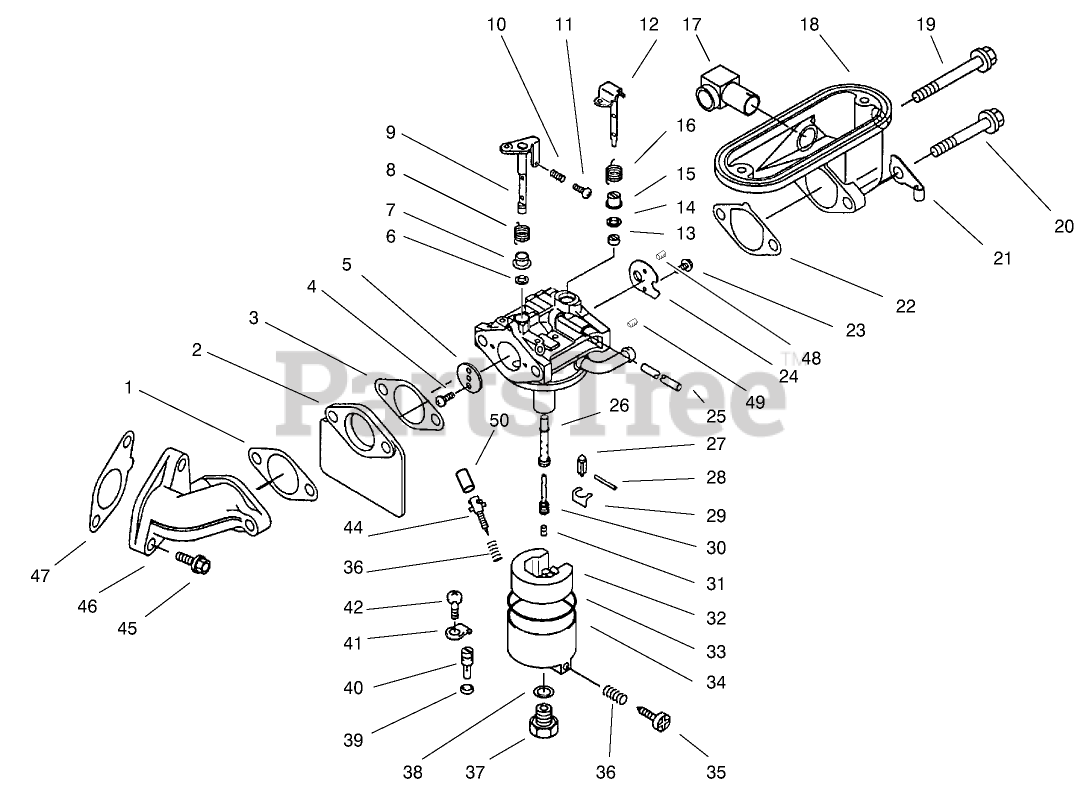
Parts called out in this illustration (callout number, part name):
1	Gasket
3	Gasket-Carburetor
4	Screw
5	Valve-Throttle #110
9	Shaft-Throttle
12	Shaft-Choke
18	Pipe-Intake
22	Gasket
23	Screw
24	Valve-Choke
25	Tube
26	Nozzle-Main
27	Valve-Float
30	Holder-Main Jet
31	Jet-Main
33	Gasket
34	Chamber-Float
35	Screw
38	Gasket
44	Screw-Pilot Air
45	Bolt-Flanged (8X25)
46	Pipe-Intake
47	Gasket-Intake Pipe
48	Jet-Air #0.9
